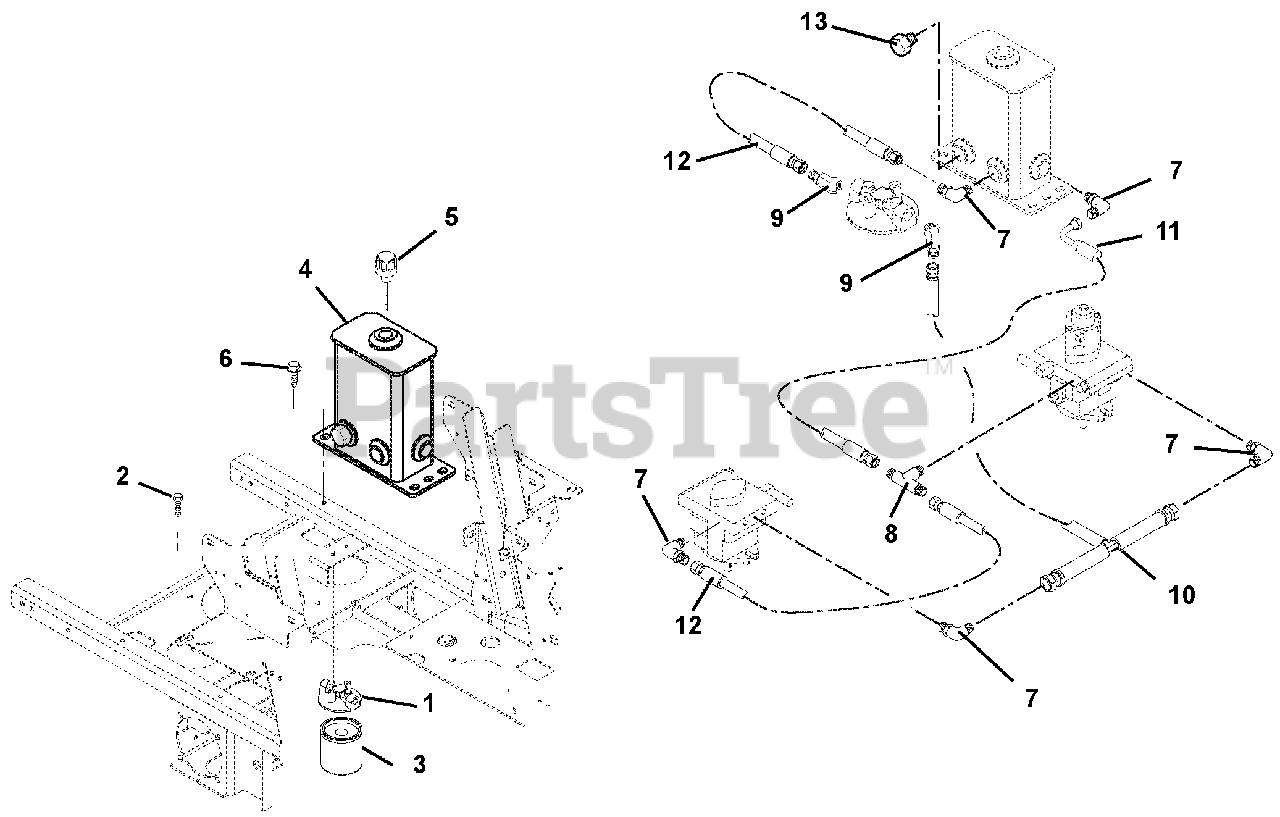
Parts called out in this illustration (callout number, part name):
1	Head, Filter
2	Bolt, Hex .25-20 x .50 Epoxy Grade 5
3	Oil Filter
4	Weldment, Hydraulic Tank
5	Hydraulic Tank Dipstick
6	Screw, Tapping .38-16 x .75 Hex Washer Head
7	Fitting, Hydraulic, 90 Degree Elbow, Steel M8F-M80
8	Fitting, Hydraulic Tee M80-M80-M80
9	Fitting, Hydraulic 45° M80-M120
10	Hose, Tee Assembly, .50
11	Hose, Hydraulic
12	Hose, Hydraulic
13	Plug, Hex, .75-16 O-Ring
